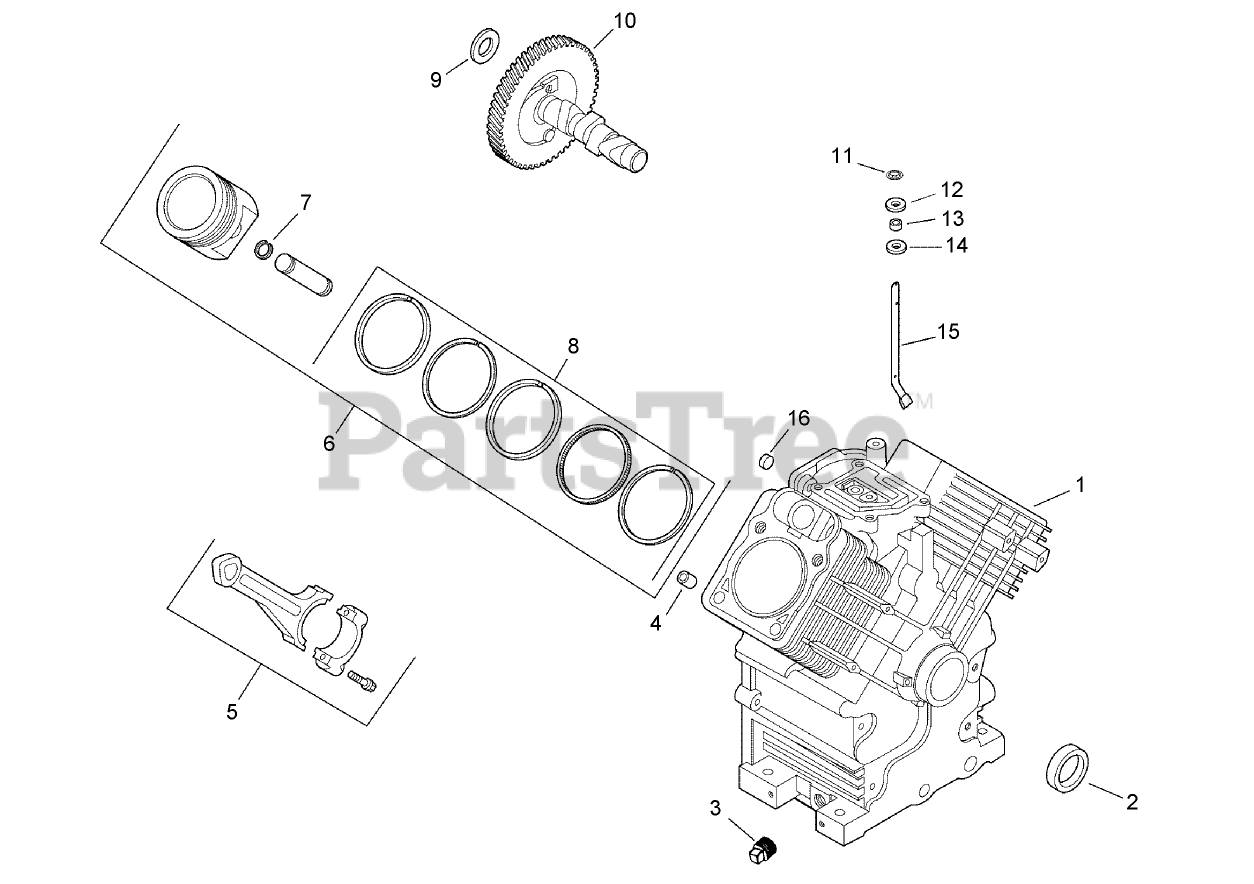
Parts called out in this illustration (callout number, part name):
2	SEAL-OIL
3	PLUG-PIPE, SQ HD (3/8)
4	Pin-Locating
5	Rod-Connecting (Standard)
5	Rod-Connecting (.25)
6	Piston w/Ring Set (Std.) (Includes 7,8)
6	Piston and Ring Set (.08)
6	Piston and Ring Set (.25)
6	Piston and Ring Set (.50)
7	RETAINER-PIN, PISTON
8	Ring Set (.25)
8	Ring Set (.50)
9	SHIM-CAMSHAFT (YELLOW .034)
9	SHIM-CAMSHAFT (RED .032)
9	SHIM-CAMSHAFT (BLACK .04)
9	SHIM-CAMSHAFT (WHITE .028)
9	SHIM-CAMSHAFT (BLUE .03)
9	SHIM-CAMSHAFT (GREEN .036)
9	SHIM-CAMSHAFT (GRAY .038)
10	CAMSHAFT KIT
11	RETAINER-RING
12	Washer-Plain (top)
13	SEAL-CROSS SHAFT, GOVERNOR
14	Washer-Flat (bottom)
15	SHAFT-CROSS, GOVERNOR
16	PLUG-CUP
